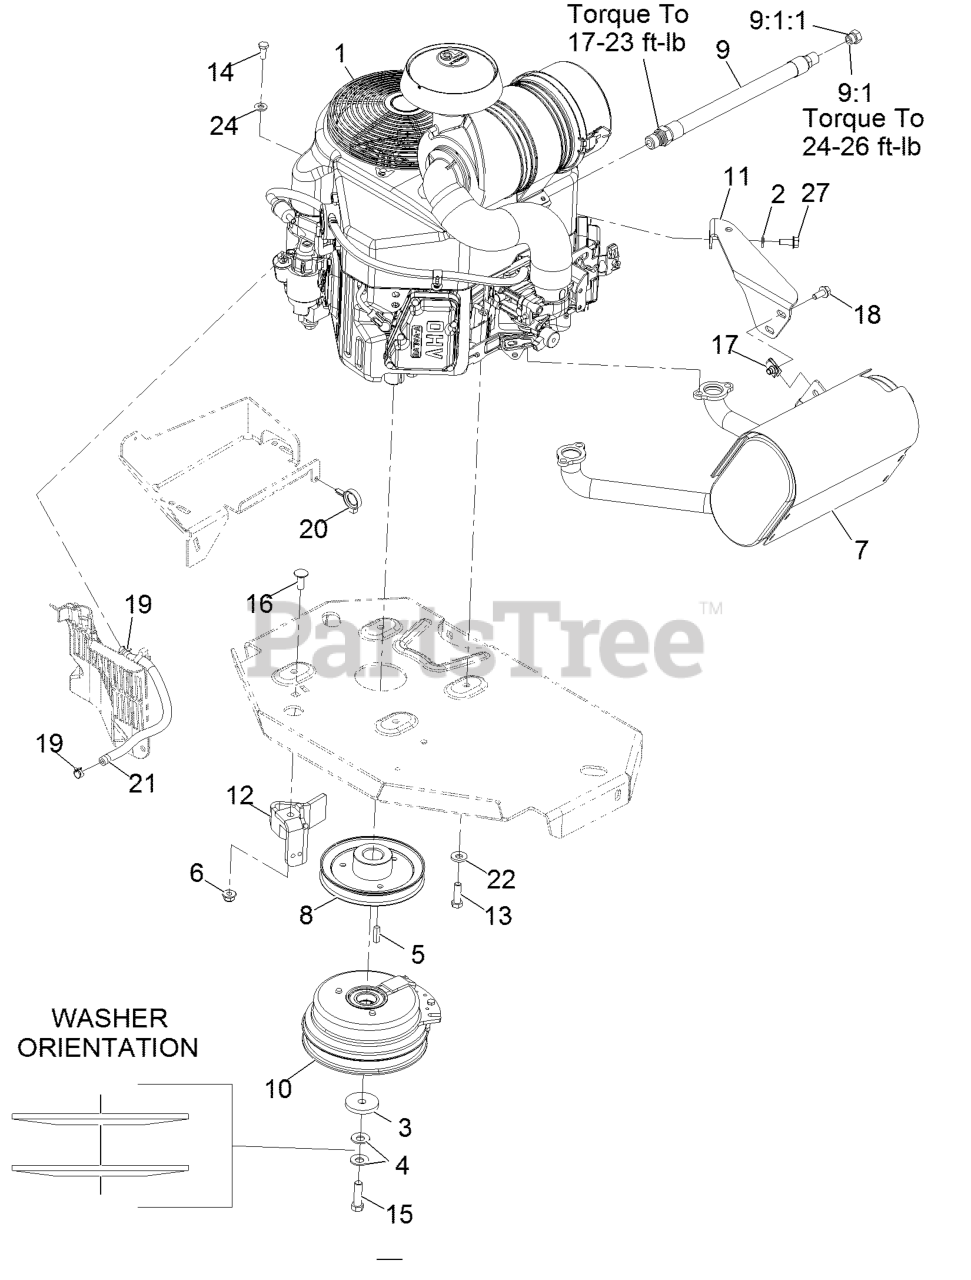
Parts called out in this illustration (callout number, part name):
2	WASHER-SPRING
3	WASHER-CLUTCH
4	WASHER-SPRING
6	NUT-HF, NI
7	MUFFLER
8	SHEAVE
9	ENGINE OIL DRAIN HOSE ASM
9:1	PLUG-HH
9:1:1	O-RING
10	CLUTCH KIT
11	BRACKET-MUFFLER
12	CLUTCH-ANCHOR
13	SCREW-HH
14	SCREW-HH
15	SCREW-HH 7/16-20 X 1 1/2 W/LOCTITE
16	SCREW-CARR
18	SCREW-HHF
19	CLAMP-HOSE
20	CLAMP-HOSE
21	HOSE-FUEL
22	WASHER-BELLEVILLE
24	WASHER-PLAIN
27	SCREW-HHF
